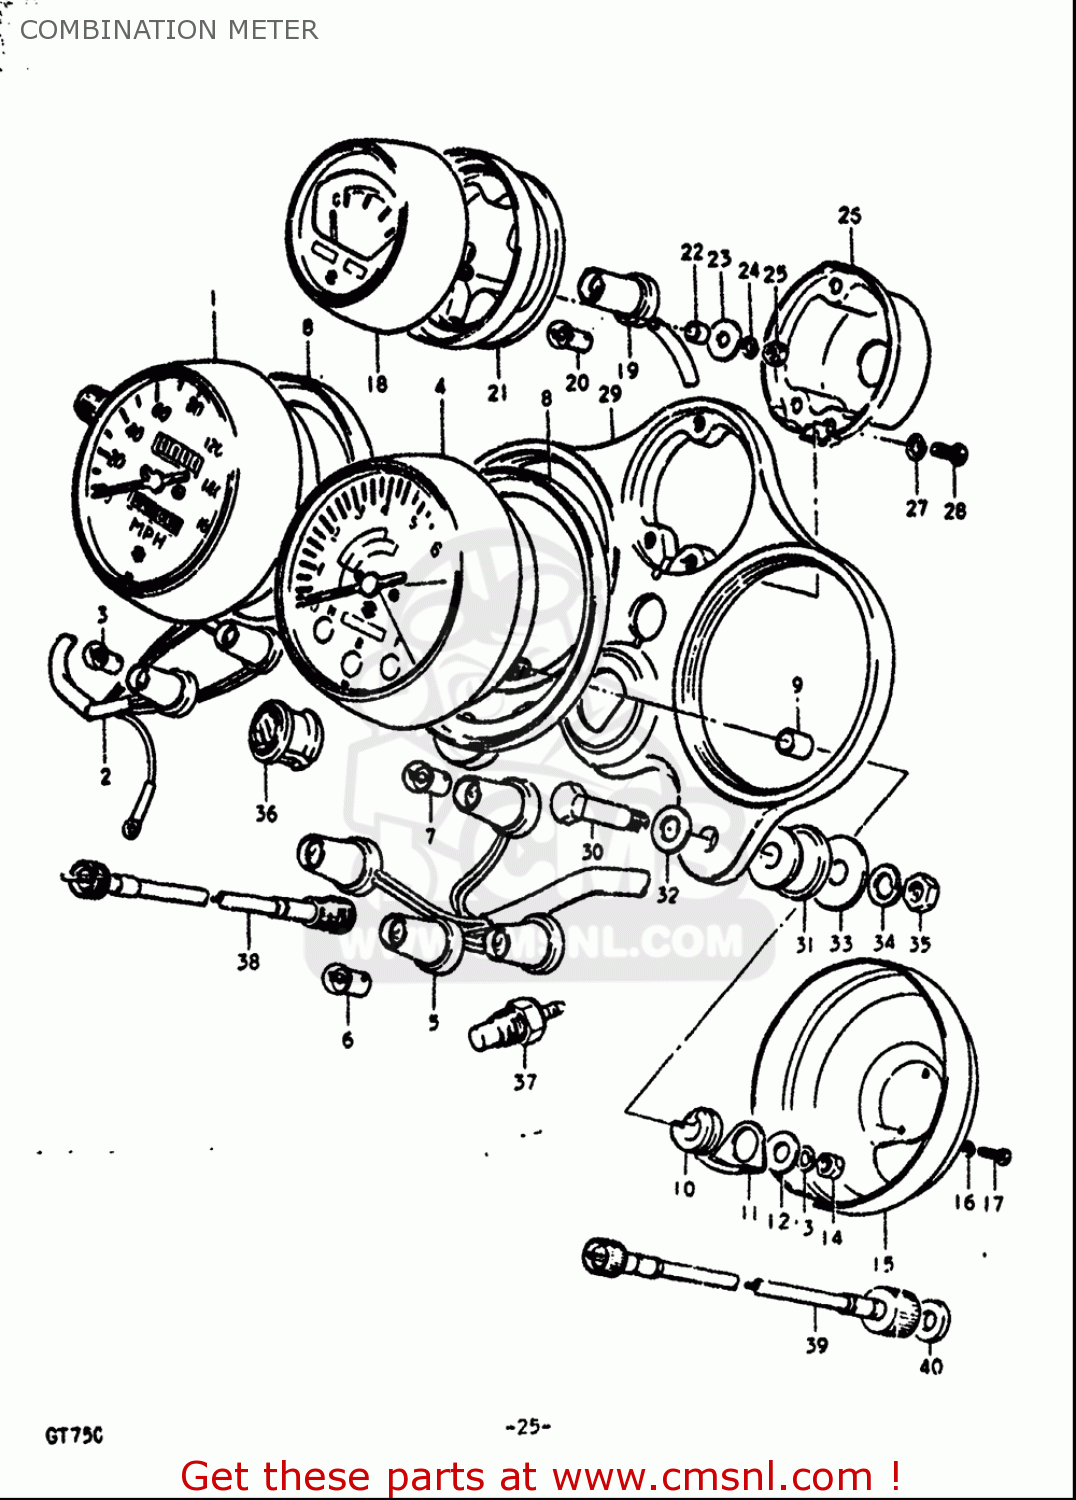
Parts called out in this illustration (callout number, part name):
3	BULB(12V3.4W,STANLEY,A72A)
6	BULB(12V3.4W,STANLEY,A72A)
7	BULB(12V1.7W,A71A)
8	CUSHION,SPEEDOMETER
12	WASHER(5.5X16X1.2)
13	WASHER,LOCK
14	NUT
16	WASHER,LOCK
17	SCREW
20	BULB(12V3.4W,STANLEY,A72A)
24	WASHER,LOCK
25	NUT
27	WASHER,LOCK
28	SCREW
31	CUSHION,METER BRACKET
32	WASHER
34	WASHER,LOCK
35	NUT
36	CAP,SPEED WARNER LAMP HOLE
37	GAUGE ASSY,WATER TEMP
39	CABLE ASSY,TACHOMETER
40	SEAL,OIL SPEEDOMETER CABLE
